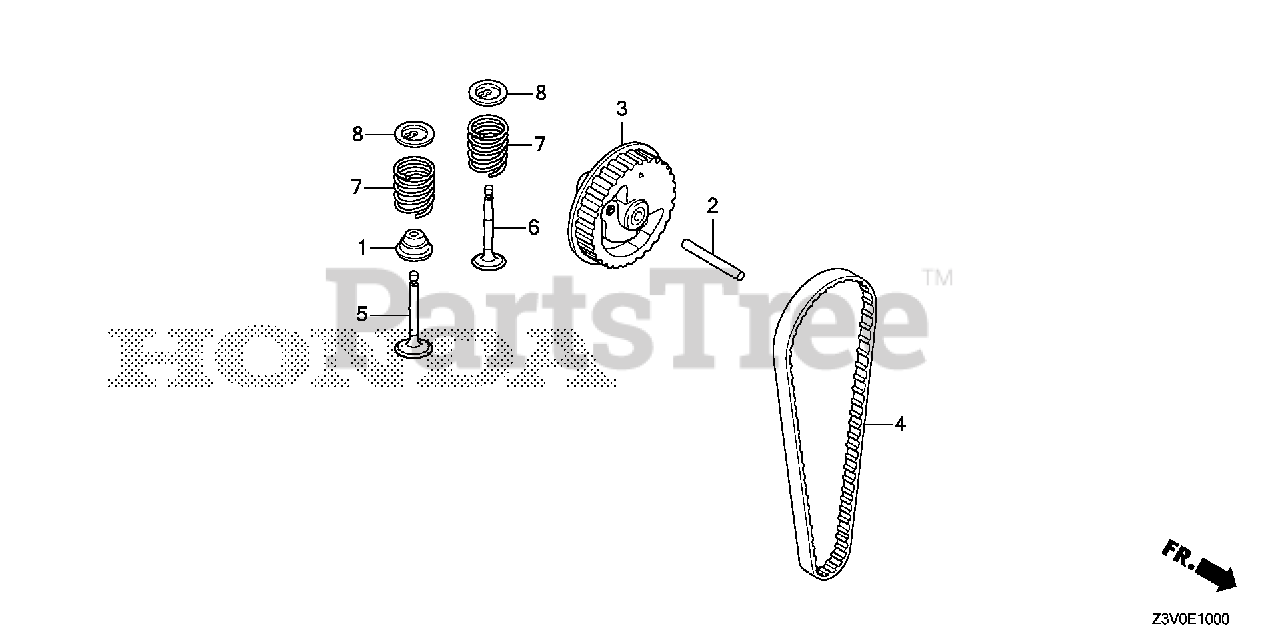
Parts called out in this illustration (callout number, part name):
1	SEAL, VALVE STEM
2	ROLLER (4X31.8)
3	PULLEY, CAMSHAFT
4	BELT, TIMING (78ZU5 G-310)
5	VALVE, IN.
6	VALVE, EX. (ZE)
6	VALVE, EX. (FE)
7	SPRING, VALVE
8	RETAINER, VALVE SPRING
